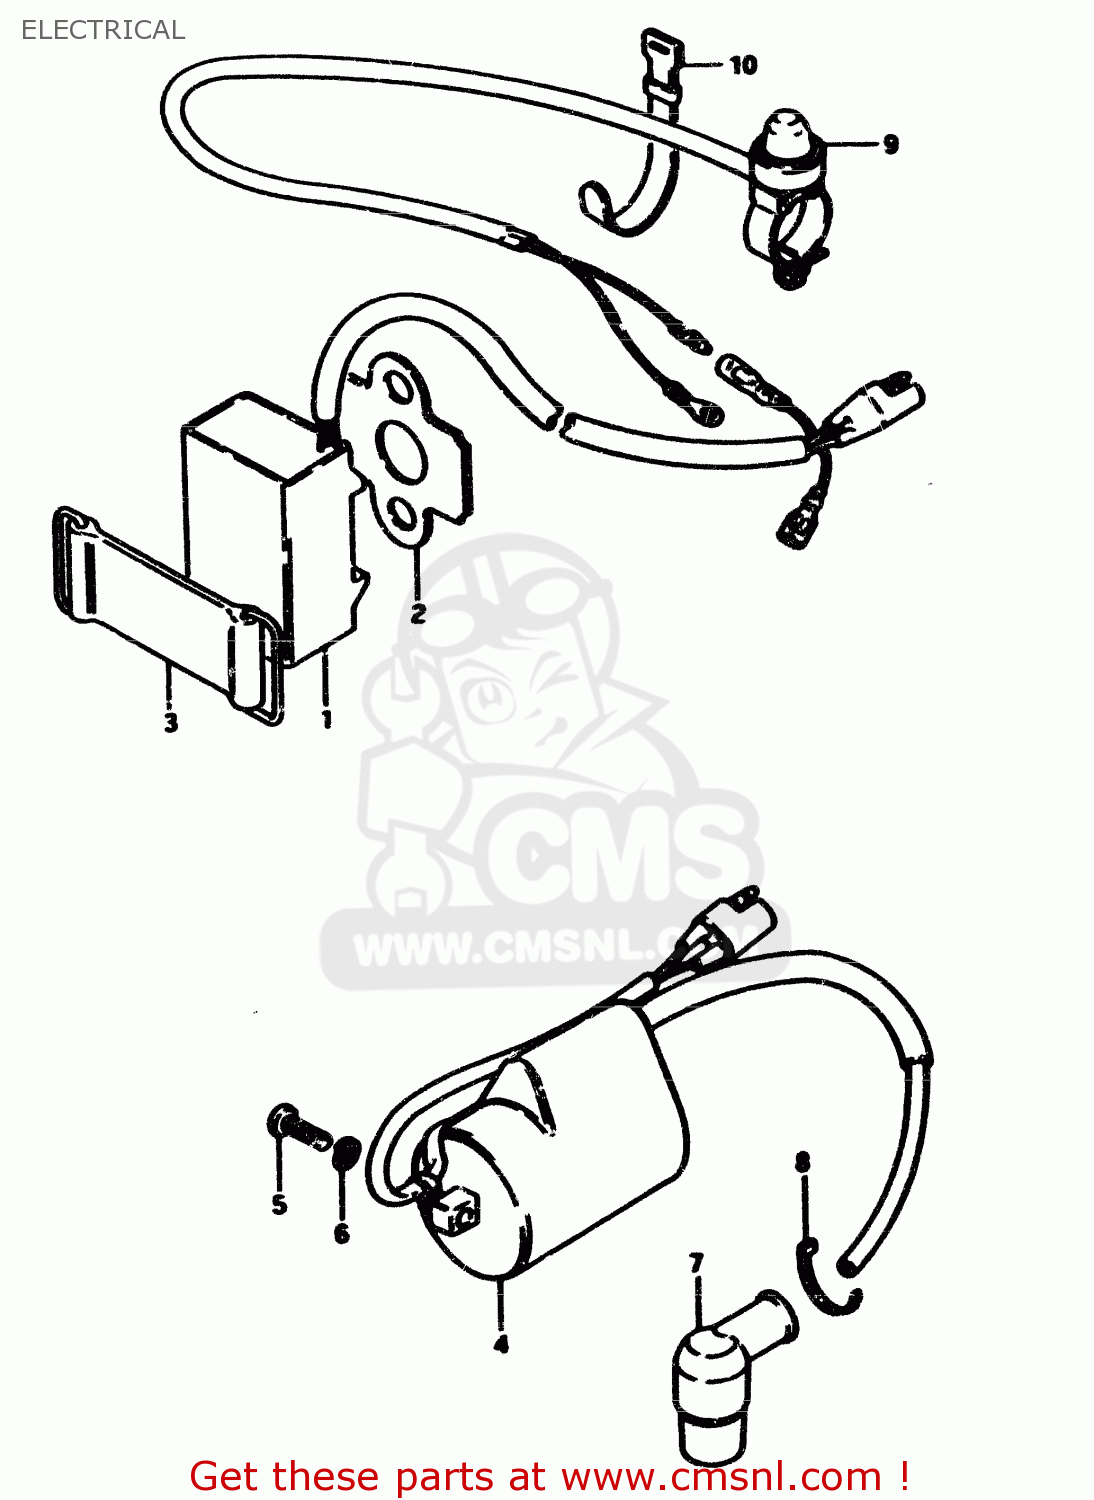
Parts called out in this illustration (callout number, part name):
1	CDI UNIT
2	PROTECTOR,CDI UNIT
3	BAND
4	COIL ASSY,IGNITION
5	SCREW 5X20
6	LOCK WASHER
7	CAP,SPARK PLUG
8	CLAMP
9	SWITCH ASSEMBLY
10	CLAMP(L:120)
